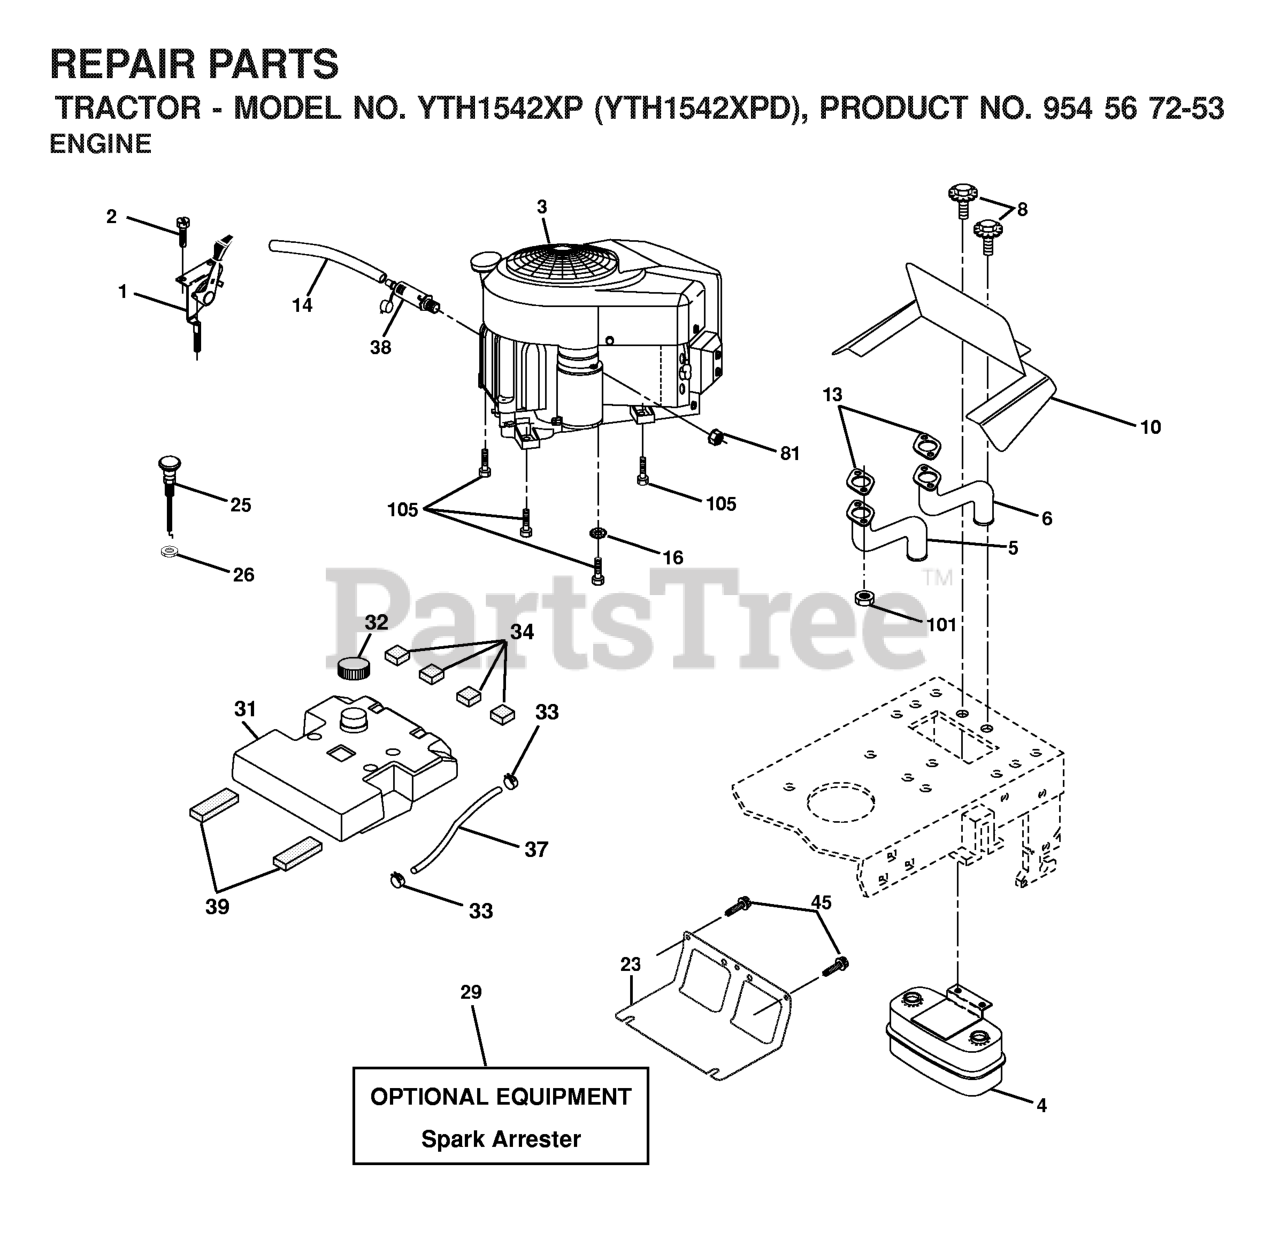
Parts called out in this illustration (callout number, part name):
1	CONTROL, THROTTLE
2	SCREW
4	MUFFLER.TWIN.CYL.LOW.TONE
5	EXHAUST.TUBE.LH.KAWASAKI.
6	EXHAUST.TUBE.RH.KAWASAKI.
8	BOLT.5/16-18UNCX3/4 W/SEMS.BLK
10	RP SHIELD HEAT MUFFLER
14	TUBE, DRAIN OIL ASM.
16	LOCKWASHER
23	SHIELD.BROWNING.DBR.GUARD
25	CHOKE CONTROL
26	Nut Keps 3/8 - 24 UNF
29	KIT.SPARK ARRESTOR 794945 B&S
31	TANK.FUEL(3.5.GAL)
32	FUEL CAP/GAUGE
33	HOSE CLAMP
34	PAD-SPACER LT
37	REPL BY 532 00 85-43
39	PAD IDLER TI
45	SCREW, 3/8-16X3/4
81	NUT
101	FLANGE NUT
105	SCREW 3/8-16X1
